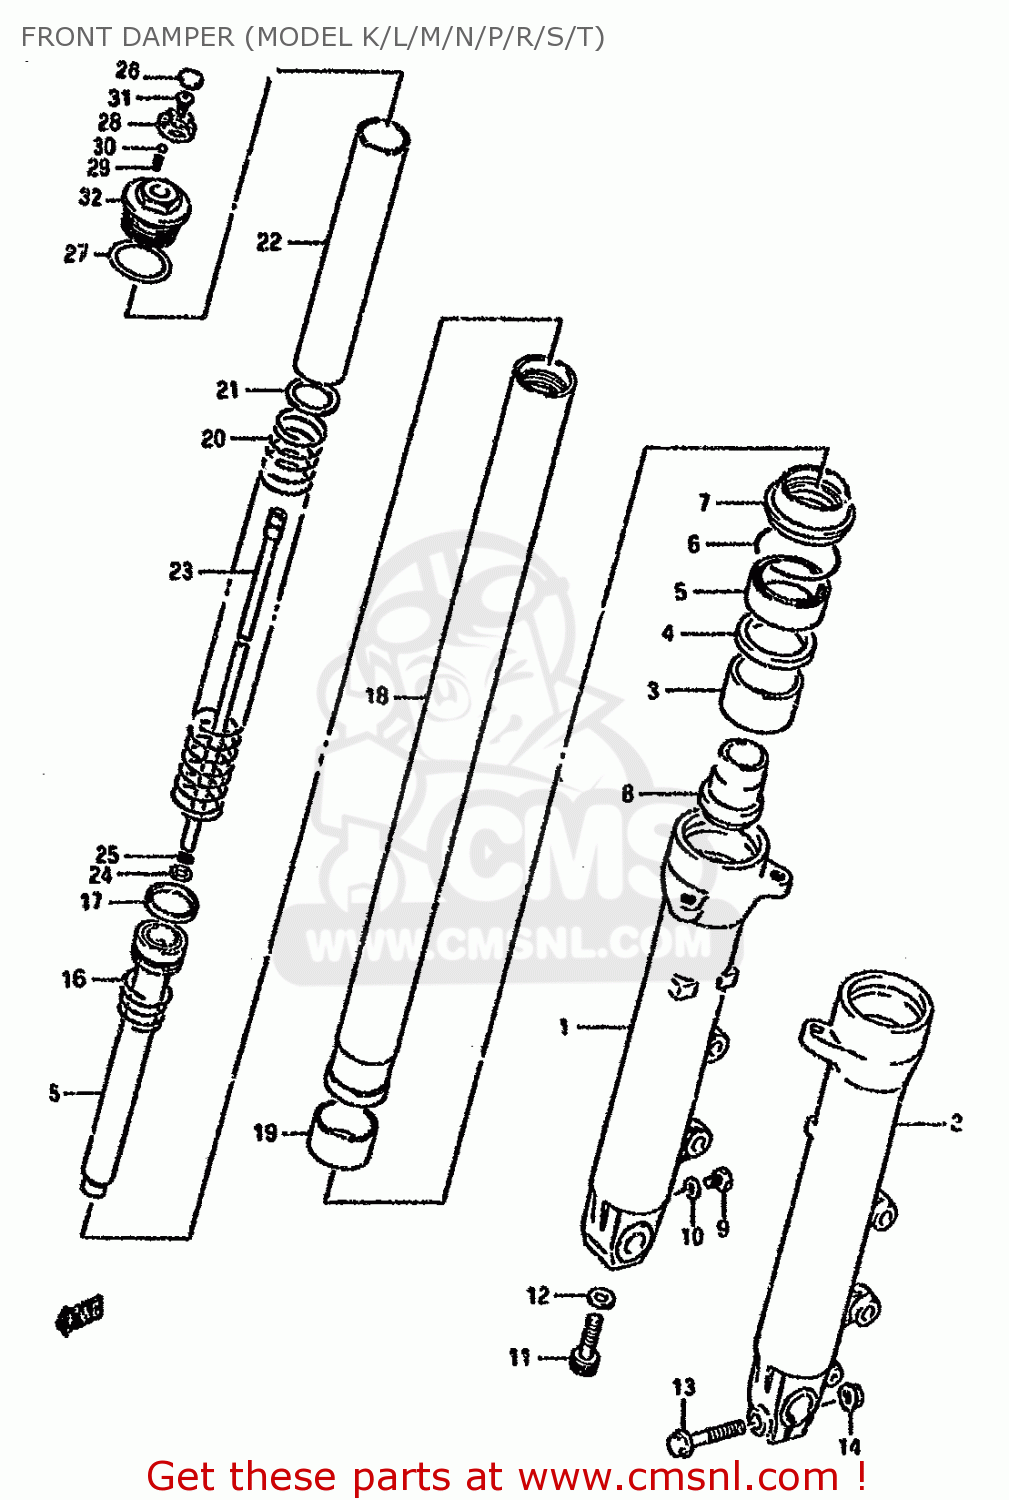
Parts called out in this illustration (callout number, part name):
1	TUBE,OUTER,R
2	TUBE,OUTER,L
3	BUSH,GUIDE
4	SPACER,SEAL
5	SEAL,OIL
6	CIRCLIP,FORK OIL SEAL
7	BOOT
8	PIECE,OIL LOCK
9	BOLT(6X8)
10	GASKET,DRAIN,PLUG (NAS)
11	BOLT(8X27)
12	GASKET (NAS)
13	BOLT
14	NUT
15	SEAT,UNDER
16	SPRING,REBOUND
17	RING,PISTON
18	TUBE,INNER
19	BUSH,SLIDE
20	SPRING,MAIN
21	JOINT,SPRING
22	SPACER,SPRING
23	ROD,INNER
24	WASHER
25	O RING
26	CAP
27	O RING
28	PLATE,ADJUSTER
29	SPRING
30	BALL
31	SCREW
32	BOLT,FORK
